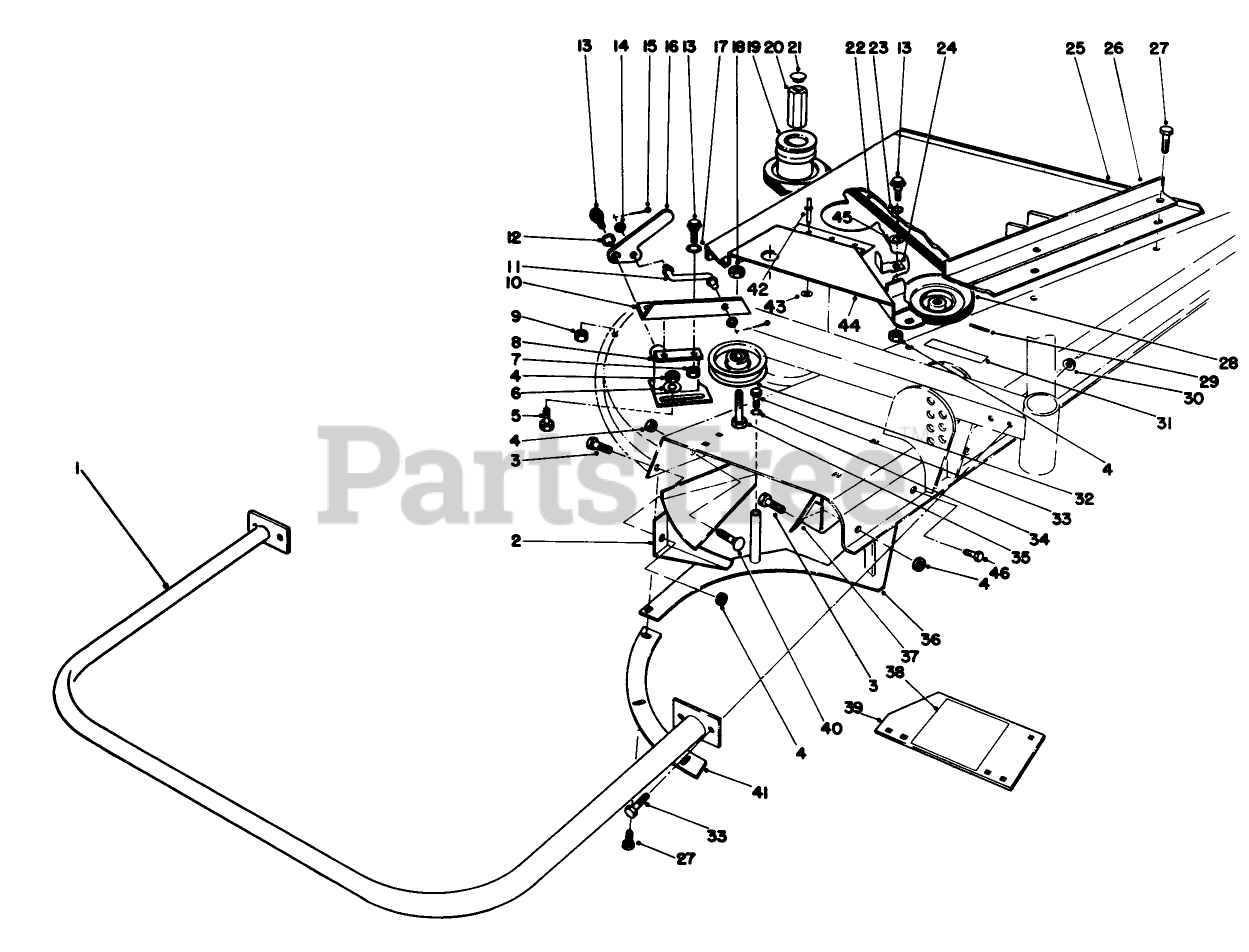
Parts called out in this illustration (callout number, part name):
1	Bumper
2	Deflector Rear
3	SCREW-HH
4	NUT-LOCK, CONE
5	SCREW-HH
6	WASHER-FLAT
7	NUT-LOCK, NI
8	Bracket-Idler
9	NUT-LOCK, CONE
10	Slide-Idler
11	Idler Rod
12	WASHER-SPRING
13	SCREW-SHOULDER
14	WASHER-PLAIN
15	PIN-COTTER
16	Lever-Idler
17	WASHER
18	NUT-LOCK, NI
19	Pulley (Splined)
20	NUT-PULLEY
21	NUT-COVER
22	V-BELT
23	WASHER-SPRING
24	Latch
25	RH COVER WA R
26	SPRING BRKT WA R
27	SCREW-HH
28	Pulley-Gear Box
29	PIN-ROLL, SLOTTED
30	NUT-LOCK, CONE
31	WARNING DECAL
32	PULLEY-IDLER
33	SCREW-HH
34	WASHER-LOCK
35	SCREW-HH
36	Rear Shelf
37	Deflector-Front
38	Decal-Caution
39	Cover Plate Assembly (Incl. Ref. #38)
40	BOLT-CARR
41	Shelf-RH
43	WASHER-FLAT
44	PULLEY COVER WA R
45	WASHER-FLAT
46	SCREW-HH
